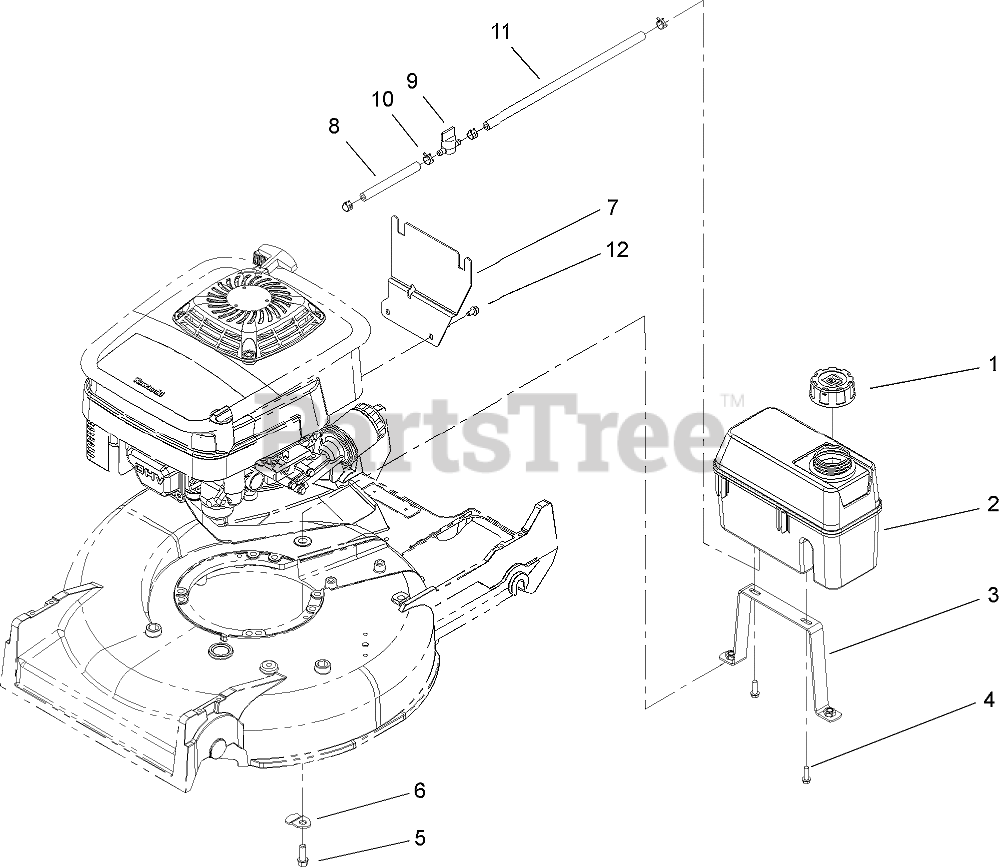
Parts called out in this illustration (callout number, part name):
1	CAP-GAS
2	Tank-Fuel
3	TANK BASE
4	SCREW-HWH
5	SCREW-TAPTITE
6	SHIELD-RETAINER
7	BRACKET-TANK
8	HOSE-FUEL
9	VALVE-FUEL
10	CLAMP-HOSE
11	HOSE-GAS
12	SCREW-HWH
